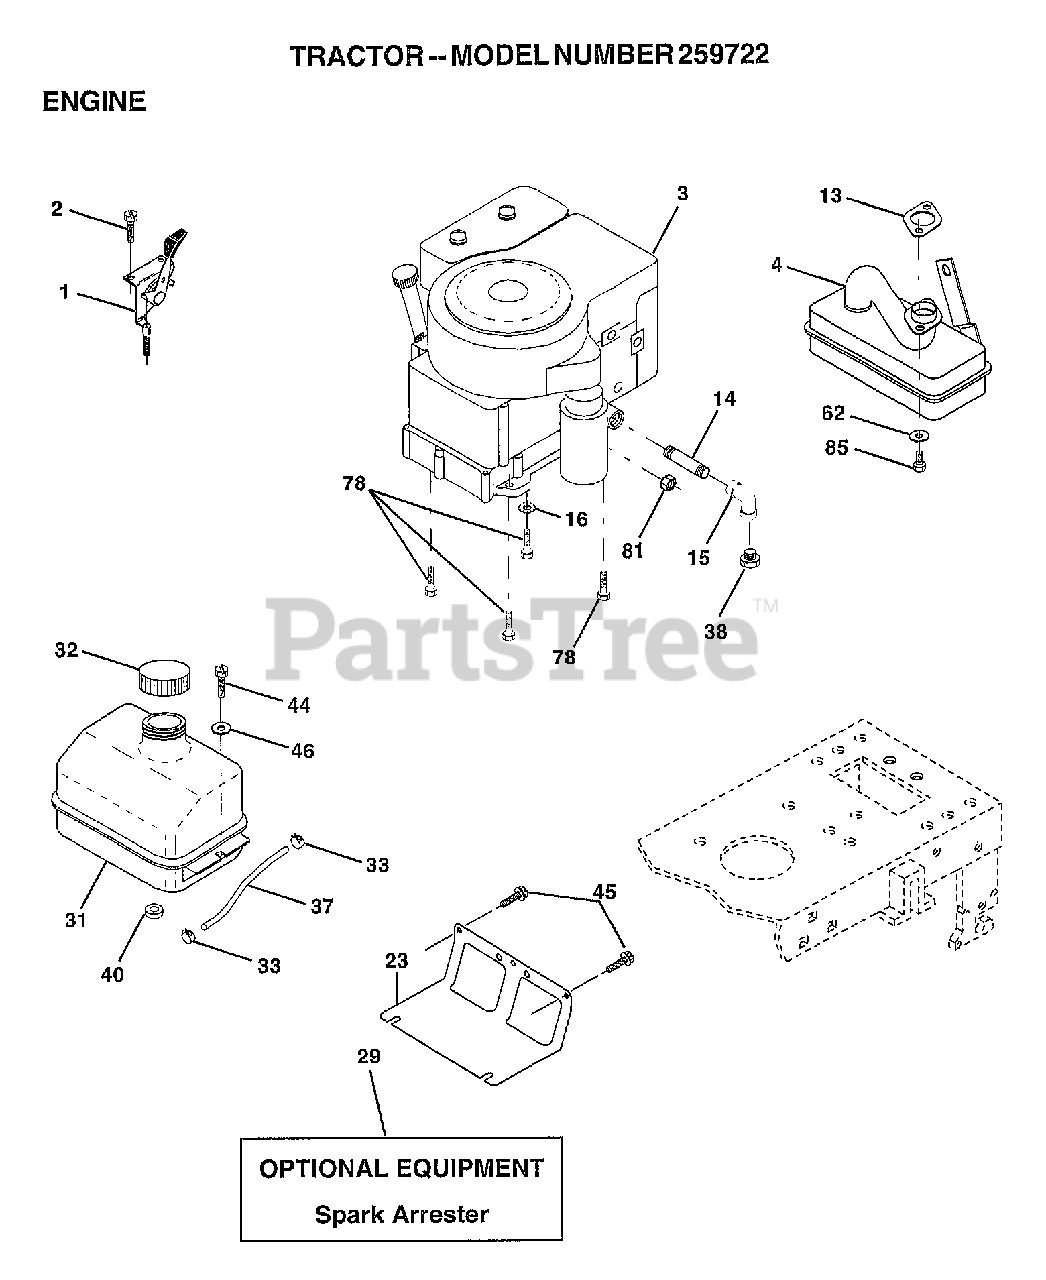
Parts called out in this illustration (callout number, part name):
1	CONTROL-THROT/CHO
2	SCREW LT
4	MUFFLER TEC. 13HP
14	PIPE NIPPLE LT
15	ELBOW
16	LOCKWASHER
23	SHIELD BROWNING
31	TANK.FUEL.LT.
32	CAP ASM FUEL TOP VENTED
33	HOSE CLAMP
37	LINE FUEL
44	SCREW HEX CRT
45	SCREW
46	WASHER
62	LOCKWASHER
72	SCREW
78	SCREW
81	NUT
